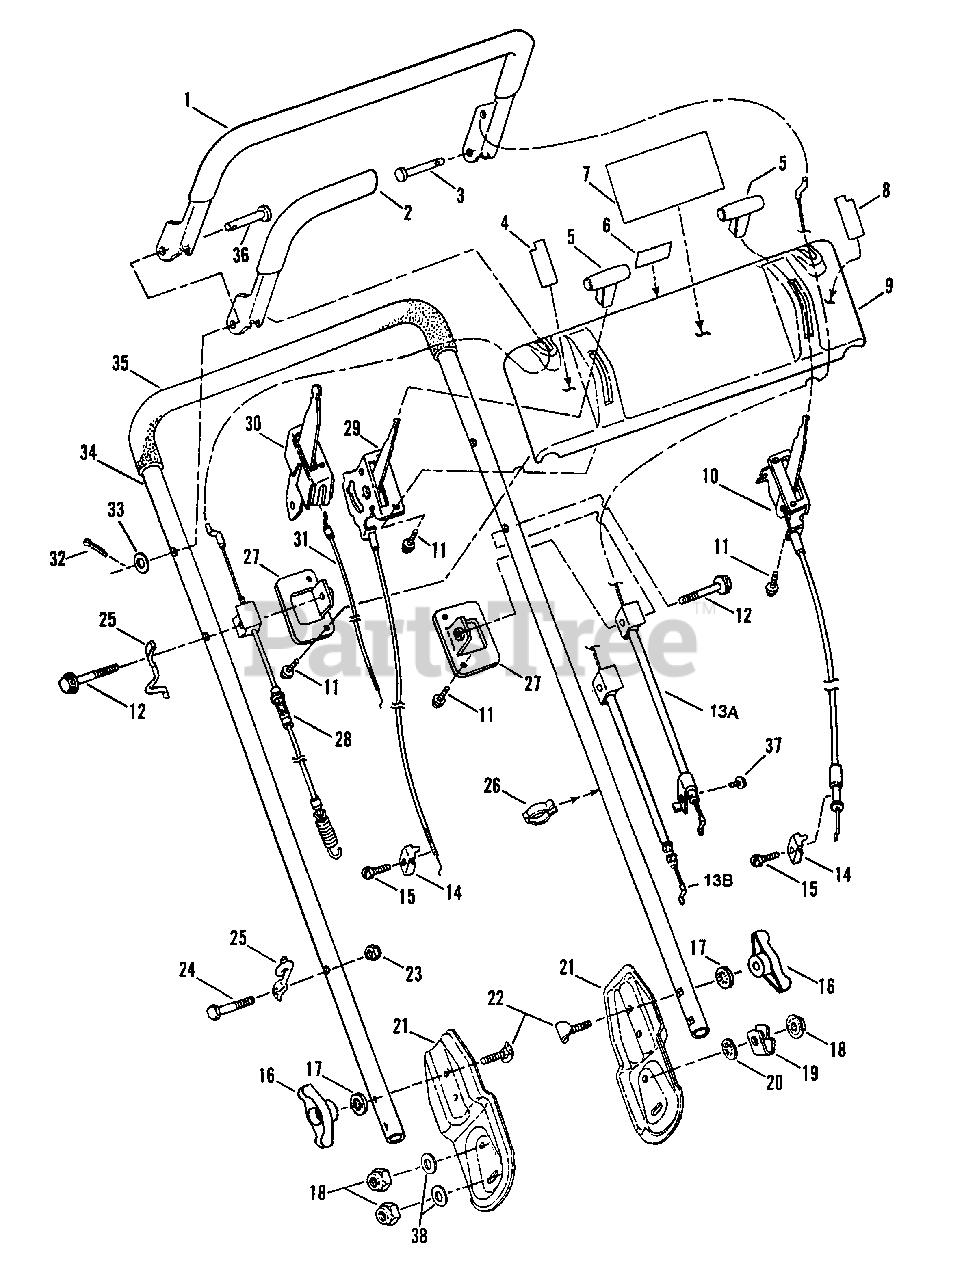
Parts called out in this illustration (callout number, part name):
1	CONTROL, Blade
2	CONTROL, Traction
3	PIN, 5/16 x 1-7/16" Clevis
4	DECAL, Engine Speed (Without Choke)
5	KNOB, Throttle Control & 3-Speed Control
6	DECAL, OPC/SP Instruction
7	DECAL, Console
8	DECAL, 3-Speed Control
9	CONSOLE, Control
10	CONTROL ASSEMBLY, 3-Speed
11	SCREW, #10-16 x 1/2" Hex Washer Head, Self-Tapping
12	SCREW, 1/4-20 x 2" Hex Washer Head, Self-Tapping
13A	CABLE ASSEMBLY, Blade Control
13B	CABLE ASSEMBLY, Blade Control
14	CLAMP, Throttle (3-Speed Control)
15	SCREW, #10-32 x 5/8 Slotted Hex Head, Self-Tapping
16	KNOB, 5/16-18 Thread
17	WASHER, 5/16 Internal Tooth Lock
18	NUT, 5/16-18 Hex Nyloc
19	CLAMP, Double Tube
20	RETAINER, 5/16 Bolt
21	BRACKET, Handle
22	SCREW, 5/16-18 x 2" Curved Head
23	NUT, 1/4-20 Hex Nyloc
24	SCREW, 1/4-20 x 1-1/2" Hex Head Cap, Grade 5
25	GUIDE, Rope
26	CLAMP, Cable
27	BRACKET, Console
28	CABLE, Traction
29	CONTROL, Throttle
30	ASSEMBLY, Throttle Control
31	CABLE, Throttle Control
32	COTTER-PIN, 1/8 x 3/4"
33	WASHER, Flat, .343 I.D. x.688 O.D.
34	HANDLE, Upper
35	GRIP, Foam
36	PIN, 5/16 x 1.71" Clevis
37	SCREW, M5 Thread, Hex Head Torx
38	WASHER, 11/32" Flat
